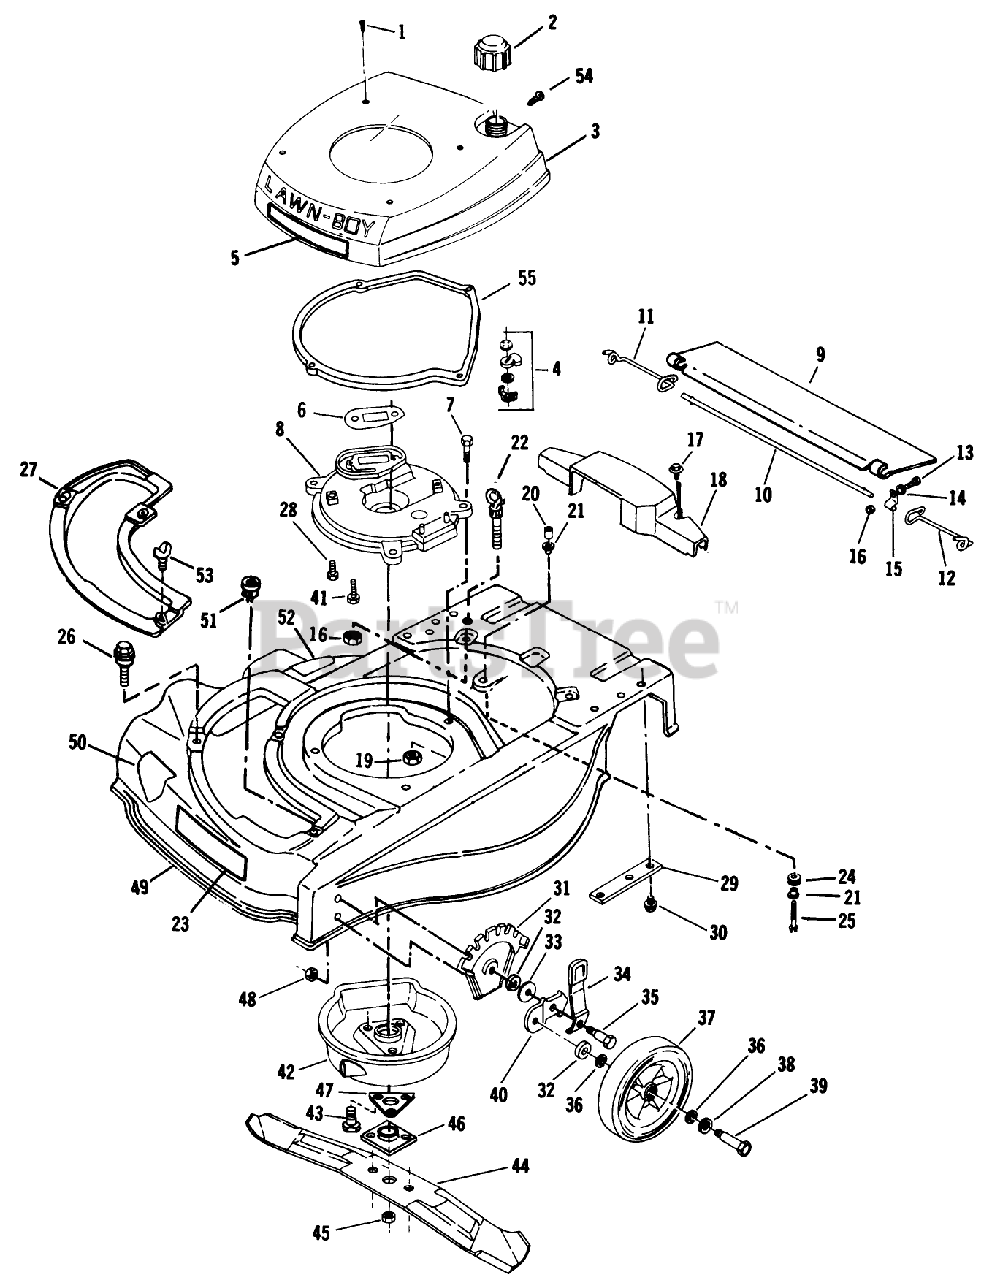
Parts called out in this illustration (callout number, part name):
1	SCREW LAWRENCE
2	FUEL CAP & INSERT
7	SCREW-HH
8	PLATE,MUFFLER F
10	ROD T/SHIELD ADV WIRE
11	SPRING;TRAILING SHIELD RH
12	SPRIG T/SHLD ASOC
14	WASHER F
15	CLAMP ROD KMC
16	LOCKNUT E
17	SCREW SEMS TRM HEX HD
19	NUT-LOCK F
20	SPACER
21	SPACER ECK PRES
22	BOLT-EYE
30	SCREW
31	PLATE HGT ADJ TRO
32	WASHER WROUGHT
33	WASHER
34	KNOB & SPRING
35	BOLT
36	WASHER
37	WHEEL & TIRE KIT
38	SPACER
39	BOLT WHEEL
41	SCREW V
43	SCREW
45	NUT-BLADE
46	PLATE AND COLLAR ASM
47	SUPPORT F
48	LOCKNUT
53	WING SCREW LAWRE
54	SCREW S
